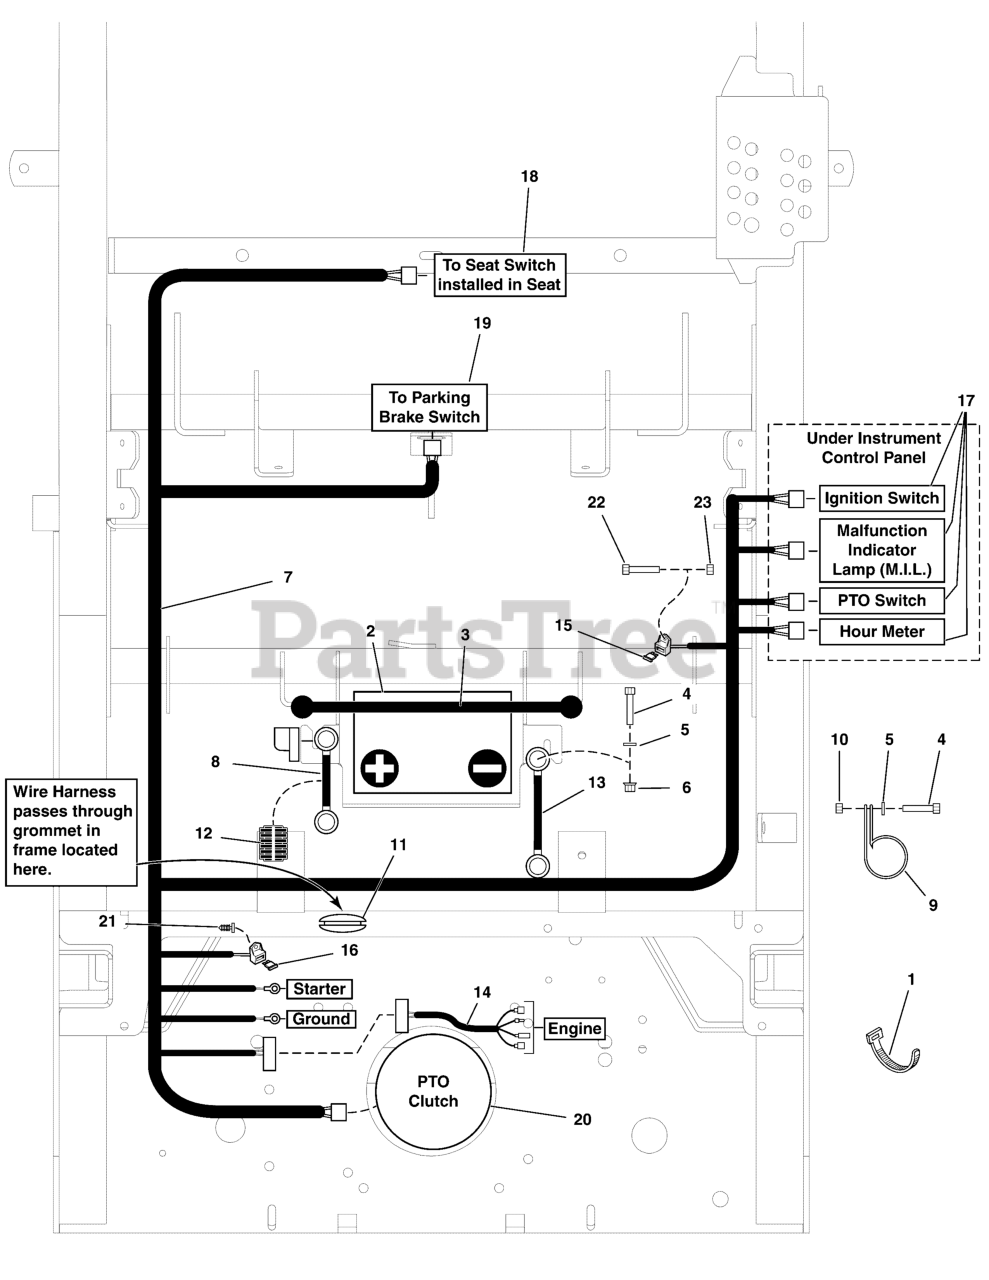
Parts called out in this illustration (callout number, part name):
1	TIE, SELF-LOCKING, 12"
2	BATTERY, 11U1L, 350 CCA
3	STRAP, BATTERY, 14 LONG, Rubber
4	BOLT, 1/4"-20 X 3/4" GD5 YZ
5	WASHER, 1/4 SAE
6	NUT, 1/4-20 HEX SERR. FLANGE
7	HARNESS, Wiring, Large ZTR
8	BATTERY CABLE, POS, 22, 1/4-5/16
9	CLAMP, VINYL INSULATED, 1.00
10	NUT, 1/4-20 Hex Nylock Flange
11	GROMMET, 2" ID
12	WIRE LOOM, 3/8 ID X 17 IN
13	BATTERY CABLE, NEG, 22, 1/4-5/16
14	WIRE HARNESS, JUMPER, KAWI - LARGE HARNE
15	FUSE, ATO, 25 AMP
16	FUSE, ATO-15 (15 AMP)(SV)
17	Refer to: Instrument Control Panel Group
18	Refer to: Seat Mount & Floor Group
19	Refer to: Parking Brake Group
20	Refer to: Engine & PTO Group
21	FIR TREE MOUNT, PACKARD
22	SCREW, #10-24 X 1/2" ROUND PHILLIPS
23	NUT, Hex, Nylon Lock, #10-24
